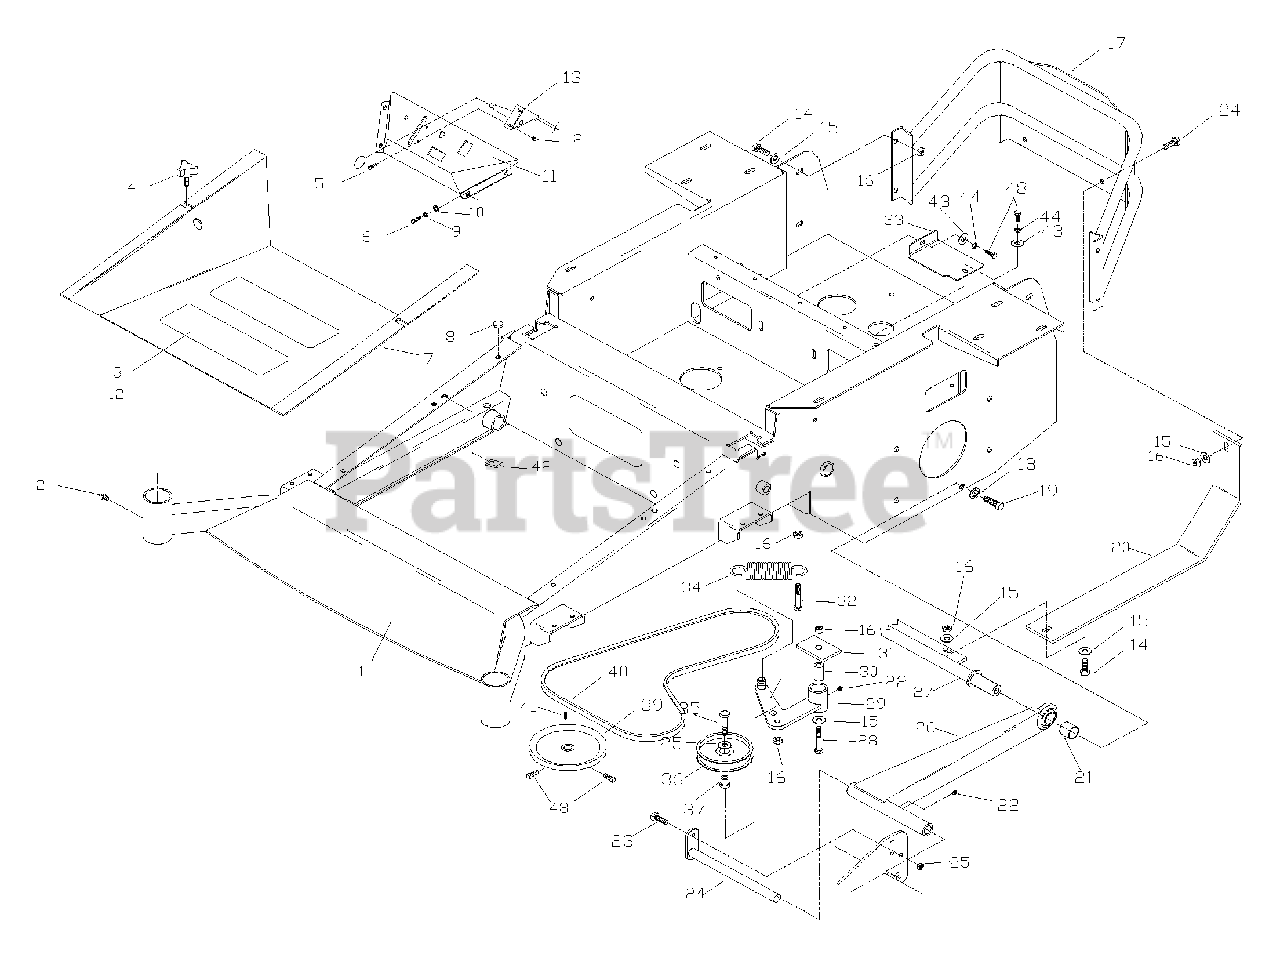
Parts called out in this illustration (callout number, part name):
1	FRAME 72" MODEL
1	FRAME 52" & 61"
2	ZERK
3	ANTI SKID PAD
4	KNOB
5	HCS #10 X 1/2
6	1/4 x 5/8 SELF TAP
7	FOOT PLATE
9	1/4 LOCK WASHER
10	1/4 FLAT WASHER
11	CONSOLE W DECAL
12	NUT #10 NYLOC
13	THROTTLE CABLE
14	HCS 3/8 X 1.0
15	3/8 FLAT WASHER
16	NUT 3/8 LOCK
17	ENGINE GUARD
18	7/16 LOCK WASHER
19	HCS 7/16 X 1.0 GD 8
20	SKID PLATE
21	STRUT SPACER, 52"/61" DECKS
22	ZERK
23	HCS 5/16 X 3/4
24	STRUT PIN, 52"/61" DECKS
25	NUT 5/16 LOCK
26	STRUT, 52"/61" DECKS
27	CROSS SHAFT 72"
27	CROSS SHAFT 52" & 61"
28	HCS 1/2 X 3.25
29	IDLER
30	PIVOT BUSHING
31	SUPPORT PLATE
32	HCS 3/8 X 1.5
33	IDLER COVER
35	HCS 3/8 X 1.75
36	IDLER PULLEY
37	IDLER BUSHING
38	5/16 X 5/8 SETSCW.
40	PUMP BELT
41	KEY 5mm SQ.
43	5/16 FLAT WASHER
44	5/16 LOCK WASHER
48	HCS 5/16 X 1.0
